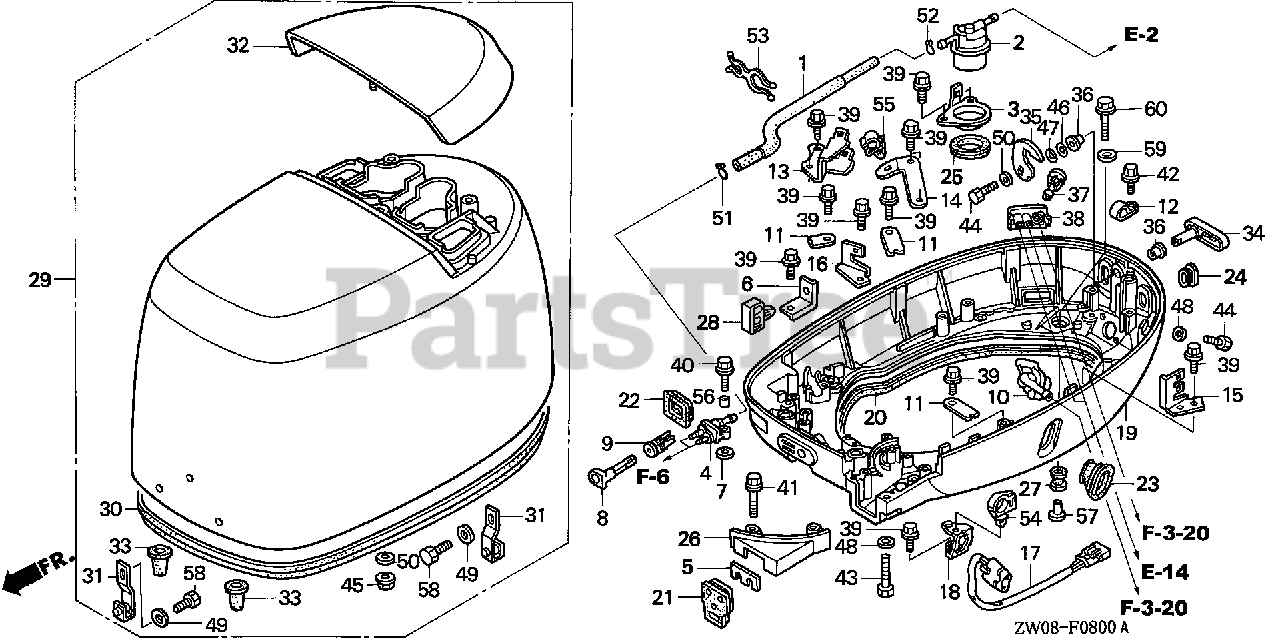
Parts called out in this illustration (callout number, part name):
1	TUBE, FUEL
2	STRAINER, FUEL (TOYO ROKI)
3	STAY, FUEL STRAINER
4	CONNECTOR ASSY., FUEL (B)
5	PLATE, REMOTE CONTROL CABLE
6	HOLDER, THROTTLE CABLE
7	WASHER, PIVOT
8	KNOB, CHOKE
9	GUIDE, CHOKE KNOB
10	JOINT, WATER INLET
11	PLATE, SHIFT SHAFT
12	CLAMP, IGNITION WIRE
13	BRACKET, CONNECTOR
14	BRACKET, CLIP A
15	BRACKET, CLIP B
16	BRACKET, HARNESS CLIP
17	SWITCH ASSY., POWER TRIM-TILT
18	STAY, POWER TILT SWITCH
19	CASE, ENGINE (LOWER) (000) *NH282MU* (OYSTER SILVER METALLIC-U)
20	SEAL, CASE (LOWER)
21	GROMMET, CASE (LOWER) (A)
22	GROMMET, CASE (LOWER) (B)
23	GROMMET, CASE (LOWER)
24	GROMMET, CASE (LOWER)
25	GROMMET, FUEL STRAINER
26	CASE, SEPARATE *NH282MU* (OYSTER SILVER METALLIC-U)
27	RUBBER, FR. CARRIER CUSHION
28	CLIP, RETURN PIPE (6MM)
29	COVER ASSY., ENGINE *NH282MU* (OYSTER SILVER METALLIC-U)
30	SEAL, ENGINE COVER
31	HOOK, ENGINE COVER
32	HANDLE, TILT *NH282MU* (OYSTER SILVER METALLIC-U)
33	DAMPER, HOOK
34	LEVER, COVER LOCK *NH282MU* (OYSTER SILVER METALLIC-U)
35	HOOK, COVER LOCK
36	BUSH, COVER LOCK
37	GROMMET, WATER CHECK
38	GROMMET, WATER CHECK
39	BOLT, FLANGE (6X12) (CT200)
40	BOLT, FLANGE (6X20)
41	BOLT, FLANGE (6X28) (CT200)
42	BOLT, FLANGE (5X10)
43	BOLT, HEX. (6X35)
44	BOLT, HEX. (6X16)
45	NUT, U (6MM) (FUSE RASHI)
46	WASHER (14MM)
47	WASHER, WAVE (14MM)
48	WASHER, PLAIN (6MM) Use up to Frame SN 4800342.
49	WASHER, PLAIN (8MM) Use up to Frame SN 4800712.
50	WASHER (6MM)
51	CLIP, TUBE (B10)
52	CLIP, TUBE (B12)
54	CLAMP, HARNESS
55	CLIP, CABLE
56	COLLAR, DISTANCE (6MM)
57	COLLAR (8.5X14.5)
58	BOLT, HEX. (8X16)
59	WASHER, PLAIN (8MM)
60	BOLT, FLANGE (8X35)
